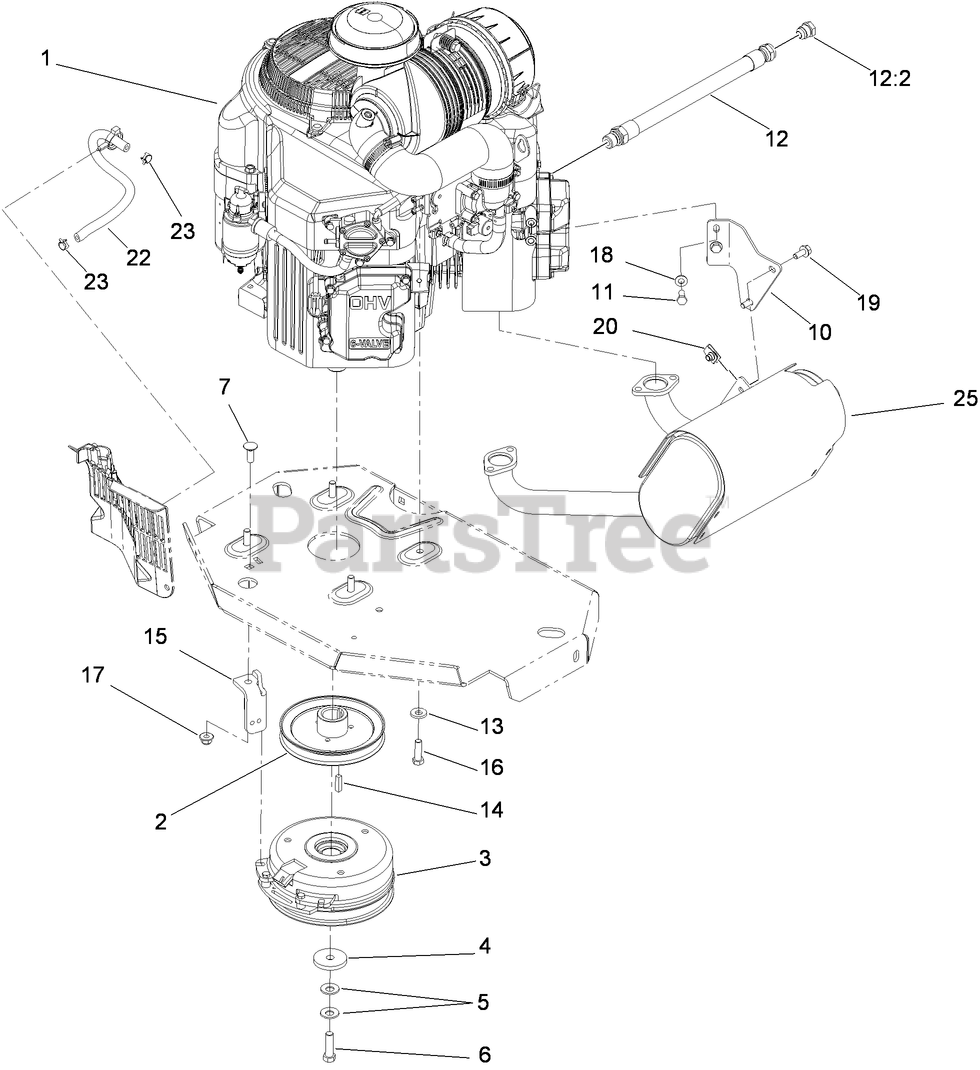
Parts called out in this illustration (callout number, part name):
2	SHEAVE
3	CLUTCH KIT
4	WASHER-CLUTCH
5	WASHER-SPRING
6	SCREW-HH, W/LOCTITE
7	SCREW-CARR
10	BRACKET-MUFFLER
11	SCREW-HH
12	OIL DRAIN HOSE ASM
13	WASHER-BELLEVILLE
15	CLUTCH-ANCHOR
16	SCREW-HH
17	NUT-HF, NI
18	WASHER-SPRING
19	SCREW-HHF
20	NUT-U
22	HOSE-FUEL
23	CLAMP-HOSE
25	MUFFLER
